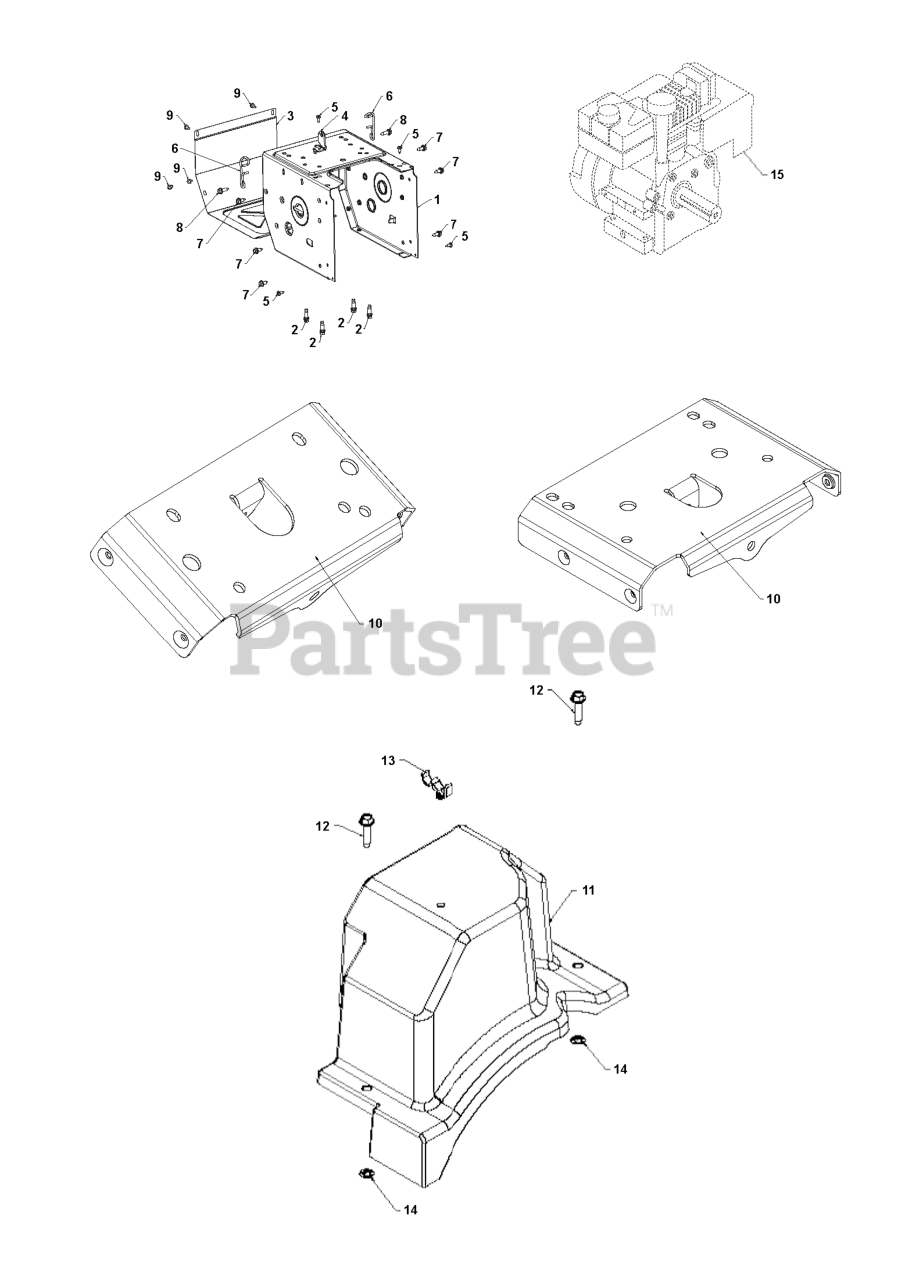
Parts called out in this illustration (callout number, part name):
1	FRAME.GEAR.CASE.ORANGE
1	FRAME MS 668
2	BOLT 3/8-16X1-1/8
3	COVER COVER.FRAME MS667 RED
3	COVER COVER.FRAME MS668 ORANGE
4	BRACKET.SHIFTER.BZP
5	SCREW 14-20 X 5/8
5	SCREW.HEX HEAD W/COLLAR 1/4-20
6	WIREFORM.SUPPORT.CABLE
7	BOLT.HEX.HD.WASHER.5/16-18X.75
8	SCREW HEX_SERR_HD_5_16-18X1.0
8	SCREW HEXAGON HEAD WITH COLLAR
9	SCREW
9	SCREW 14-20 X 5/8
9	SCREW.HEX HEAD W/COLLAR 1/4-20
10	BRACKET.FRAME.SUPPORT.BLACK
10	BRACKET.FRAME.SUP.LARGEENG.BLA
11	COVER COVER.BELT
11	COVER BELT ASM. LOW CRANK
12	SCREW HEX WASH THDRL BLK 1_4-
14	PALNUT 1/4
15	LCT.208CC.STORMFORCE2.50ST/CAN
15	ENGINE LCT 208CC 6.3HP DSST OP
15	ENGINE RATO 212CC (CARB)
